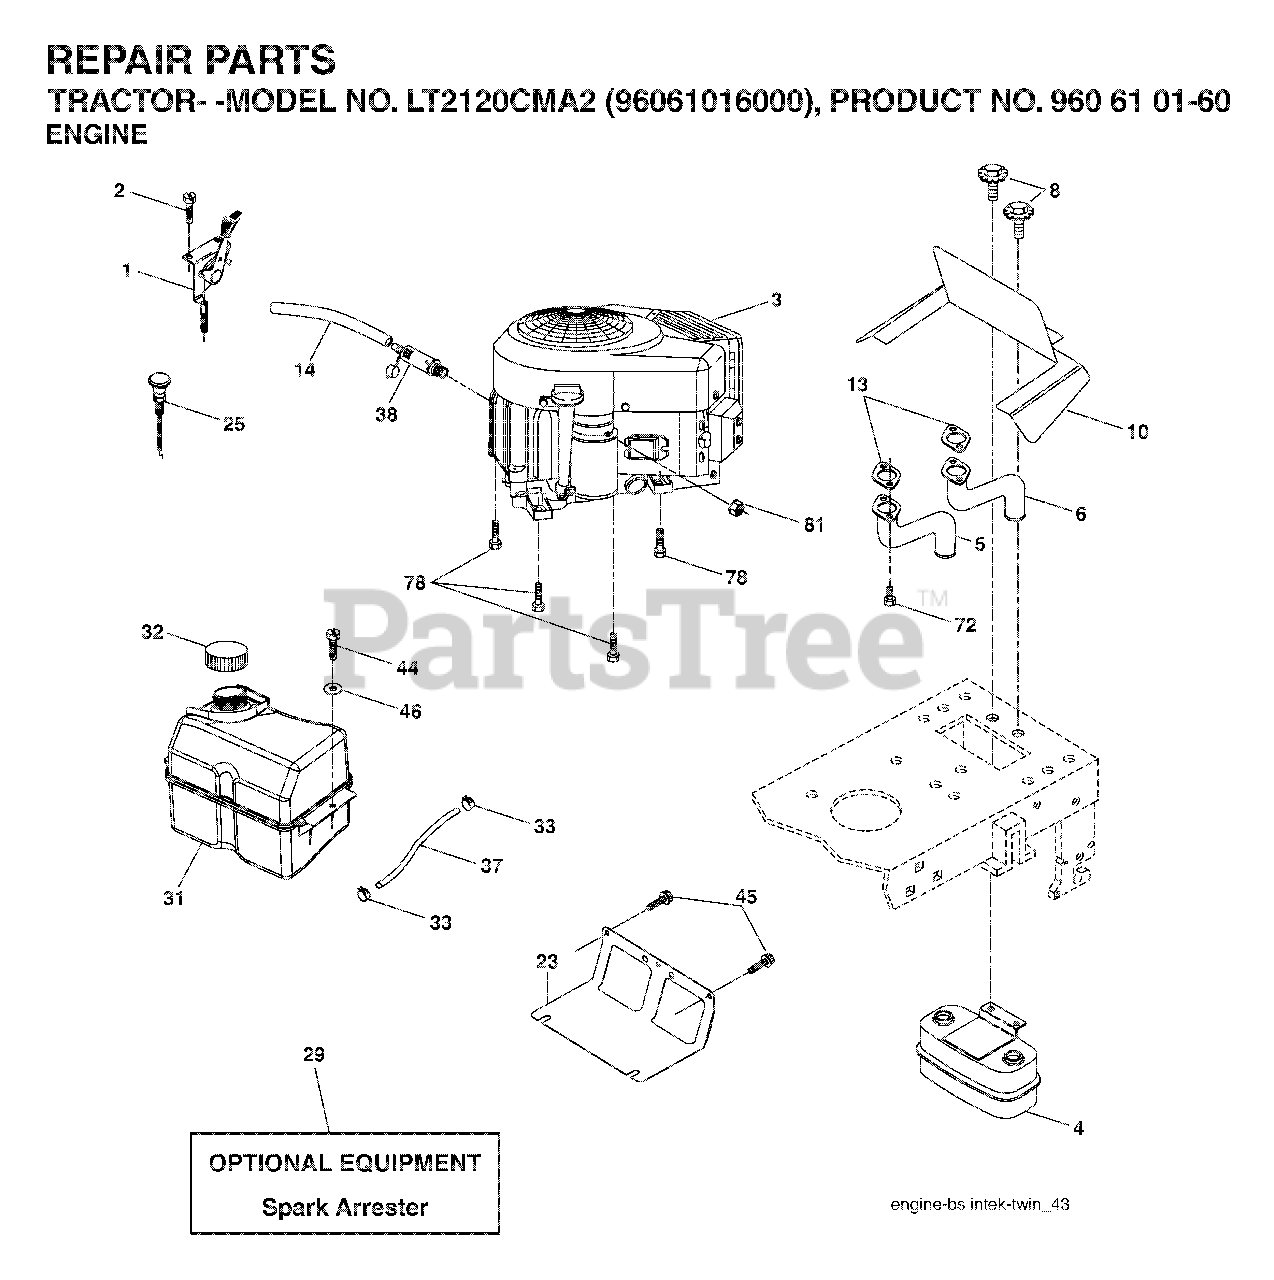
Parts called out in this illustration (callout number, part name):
1	THROTTLE CABLE
2	SCREW
4	MUFFLER.TWIN.CYL.LOW.TONE
5	TUBE MANIFOLD LH
6	EXHAUST TUBE RH
8	BOLT, 5/16-18 X 1 3/4
10	SHIELD.BROWNING.B&S
13	GASKET.MUFFLER
14	TUBE, DRAIN OIL ASM.
23	SHEILD.BROWNING.DBR.GUARD
25	CONTROL CHOKE
29	ARRESTER SPARK (OPTIONAL)
31	TANK FUEL
32	FUEL CAP
33	HOSE CLAMP
37	LINE.FUEL.20
38	PLUG DRAIN OIL EASY
44	SCREW HEXWSHR 1/4-20X3/4
45	SCREW, 3/8-16X3/4
72	SCREW.SOCKET.HEAD.5/16-18
78	SCREW.3/8-16
81	NUT
